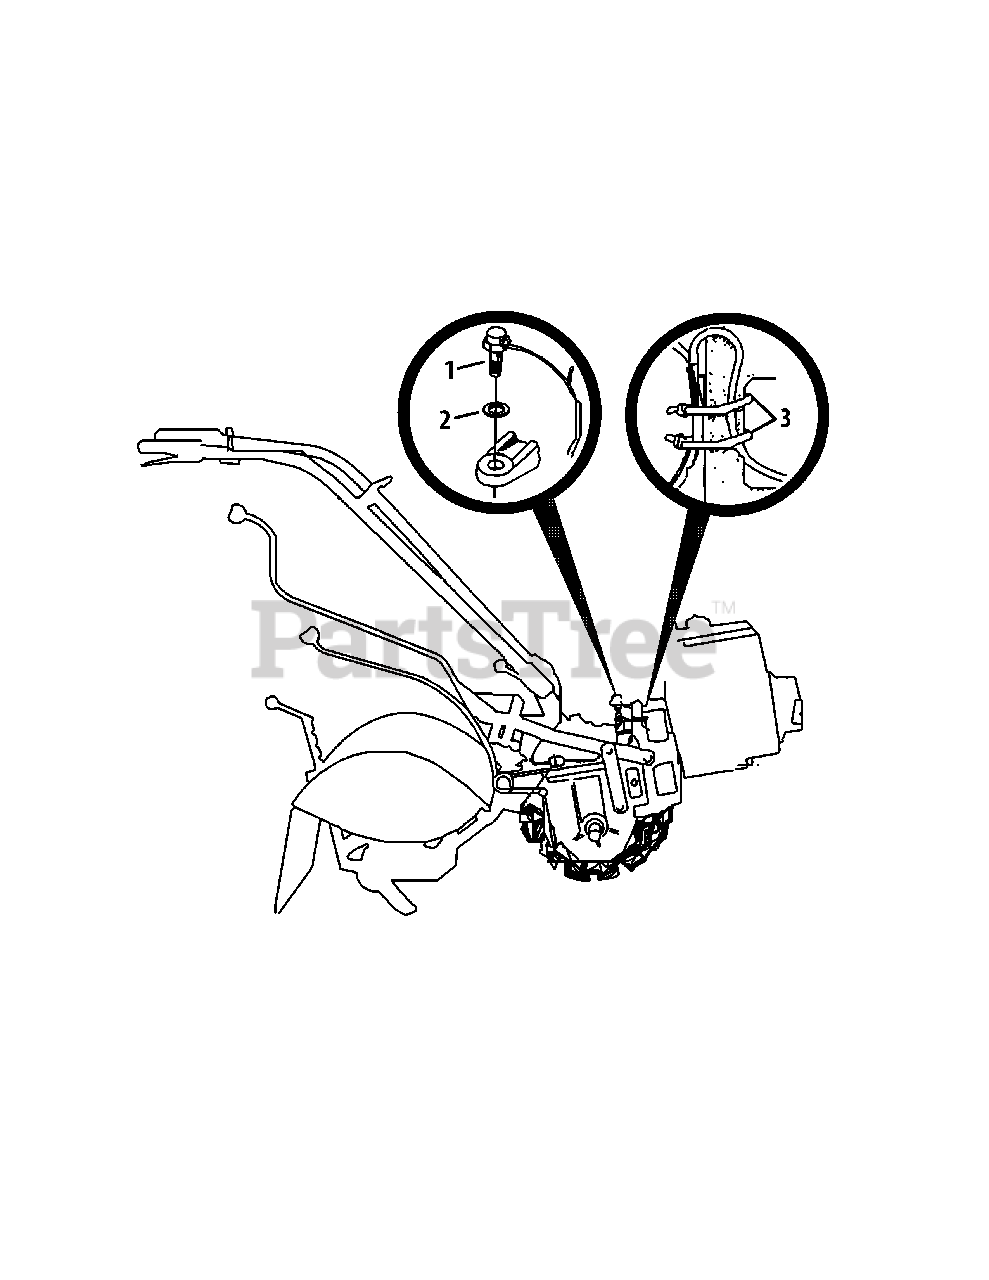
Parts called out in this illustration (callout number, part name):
1	PTO Switch
2	Internal L-Washer, 9/16"
3	Plastic Tie
